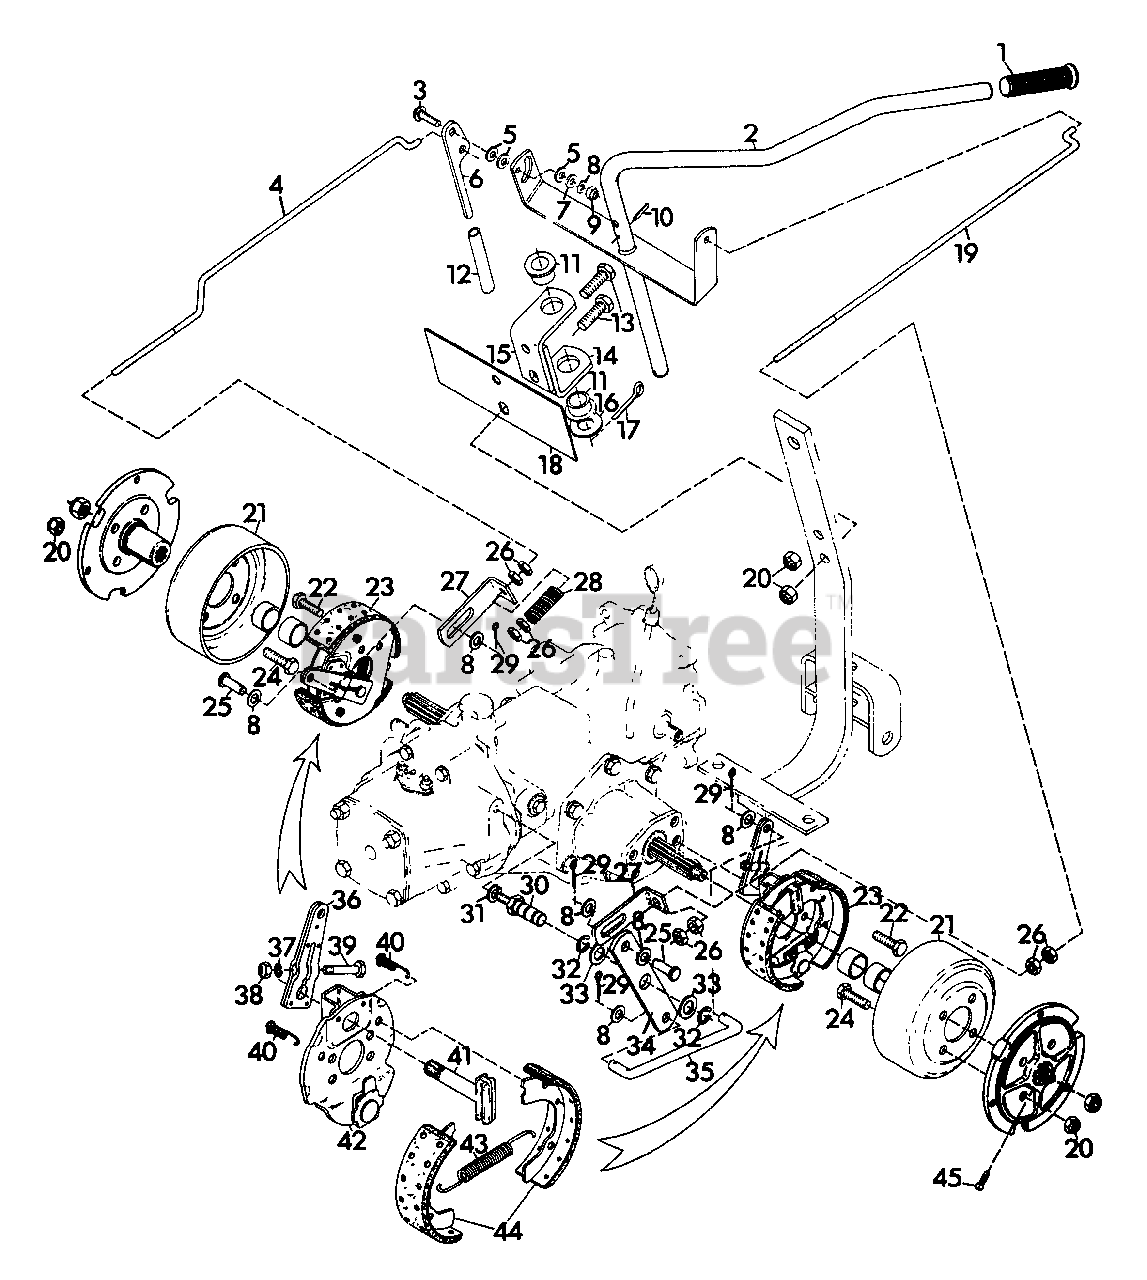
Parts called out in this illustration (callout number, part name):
1	Grip, Handlebar
2	Weldment, Brake Handlebar
3	Bolt, 3/8-16 x 1.50 Carriage
4	Rod, Brake
5	Washer, Nylon .375 x .75 x .060
6	Handle, Parking Brake
7	Washer, Rubber .375 x .75 x .125
8	Washer, flat .406 x .812 x .065
9	Nut, Lock 3/8-16
10	Pin, Spring .31 x 2.00
11	Bushing, Pivot
12	Grip, Brake Handle
13	Bolt, Hex 1/2-13 x 2.00
14	Bracket, Brake Handle
15	Bracket, Brake Handle
16	Washer, Flat 1.063 x 2.00 x .634
17	Pin, Cotter .188 x 1.50
18	Plate, Instruction
19	Rod, Brake L. H.
20	Nut, Lock 1/2-13
21	Drum, 7 x 1.75
22	Bolt, Hex 3/8-16 x .875
23	Brake, 7 x 1.75 Mechanical
24	Bolt, Hex 1/2-13 x1.375
25	Pin, Clevis .375 x .750
26	Nut, Jam 3/8-16
27	Bracket, Adjustment
28	Spring, Compression
29	Pin, Cotter .09 x .75
30	Stud, Pivot
31	Washer, Lock 1/2 Reg.
32	E-Ring, .625 Shaft
33	Washer, Flat .565 x 1.312 x .095
34	Plate, Pivot
35	Rod, Brake Link
36	Arm, Cam Lever
37	Washer, Lock 5/16 Reg.
38	Nut, Hex 5/16-24
39	Bolt, Hex 5/16-24 x 1.75
40	Spring, Shoe Retaining
41	Cam, Brake
42	Plate, Back
43	Spring, Shoe Return
44	Kit, Brake Shoe
45	Screw, Set 7/16-14 x .75 CPSH
